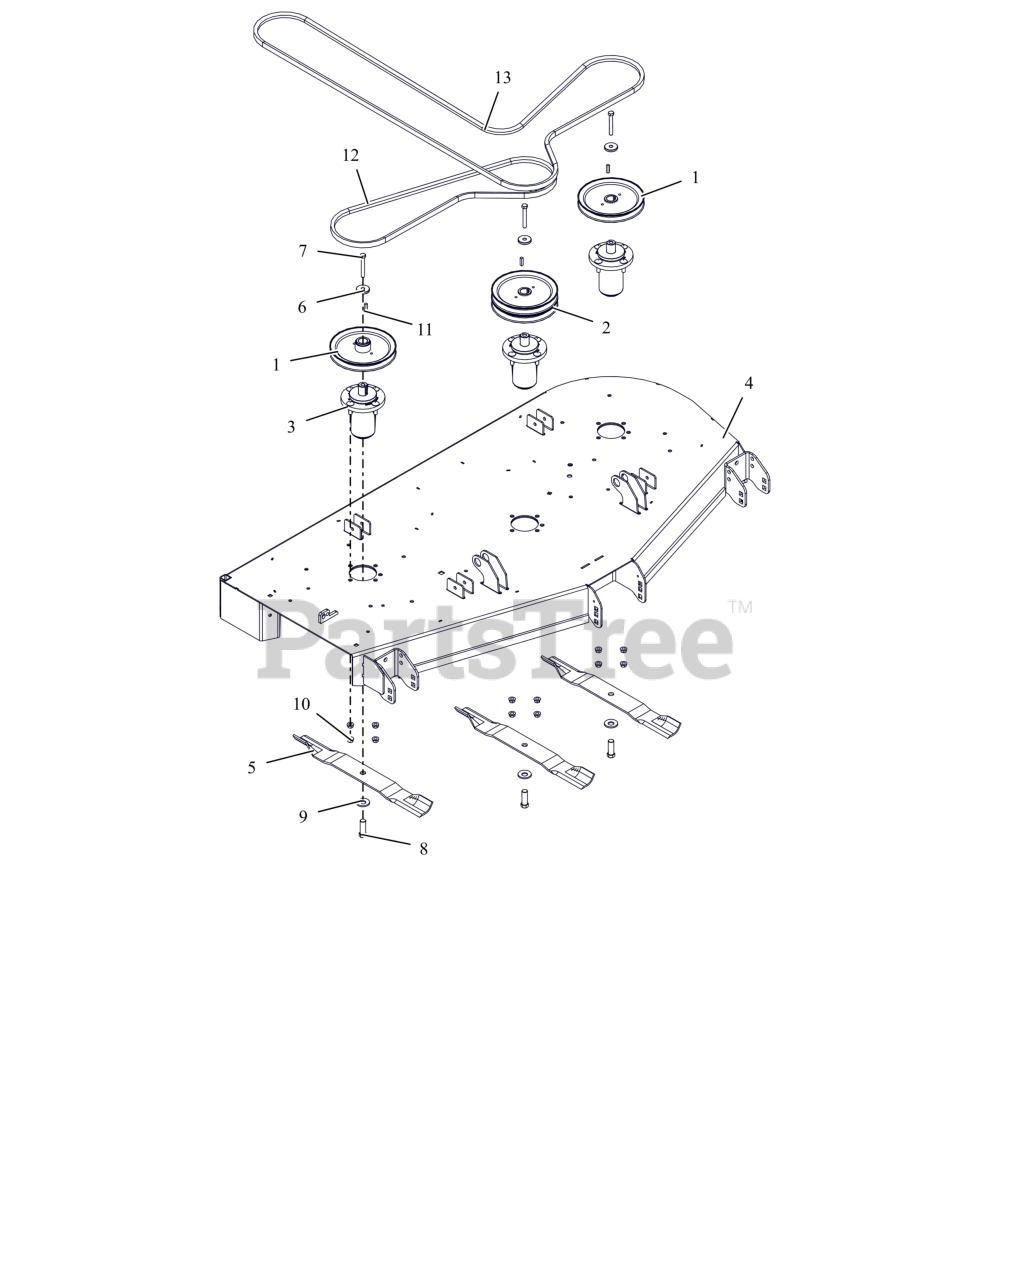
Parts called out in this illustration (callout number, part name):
1	PULLEY, V-7.50 OD X 1"ID
2	PULLEY, DOUBLE 1"X7.50"&7.50" (BLACK)
3	ASM, MAINT FREE ALUM SPINDLE
4	KIT,DECK-60" W/DECALS-GRAVELY
5	BLADE, 20.5"
6	RETAINER, SHEAVE
7	BLT, HEX .38-16X2.75 G8 ZCC
8	BLT, HEX .62-18X1.75 G8 ZCC
9	WSHR-BLVL .669X1.535X.138
10	NUT-LK-CTR-FLG .375-16 GF ZCC
11	KEY, SQ .25X.25X1.00 RC 40-50
12	V-BELT, B-COGGED
13	V-BELT, HB SECTION
